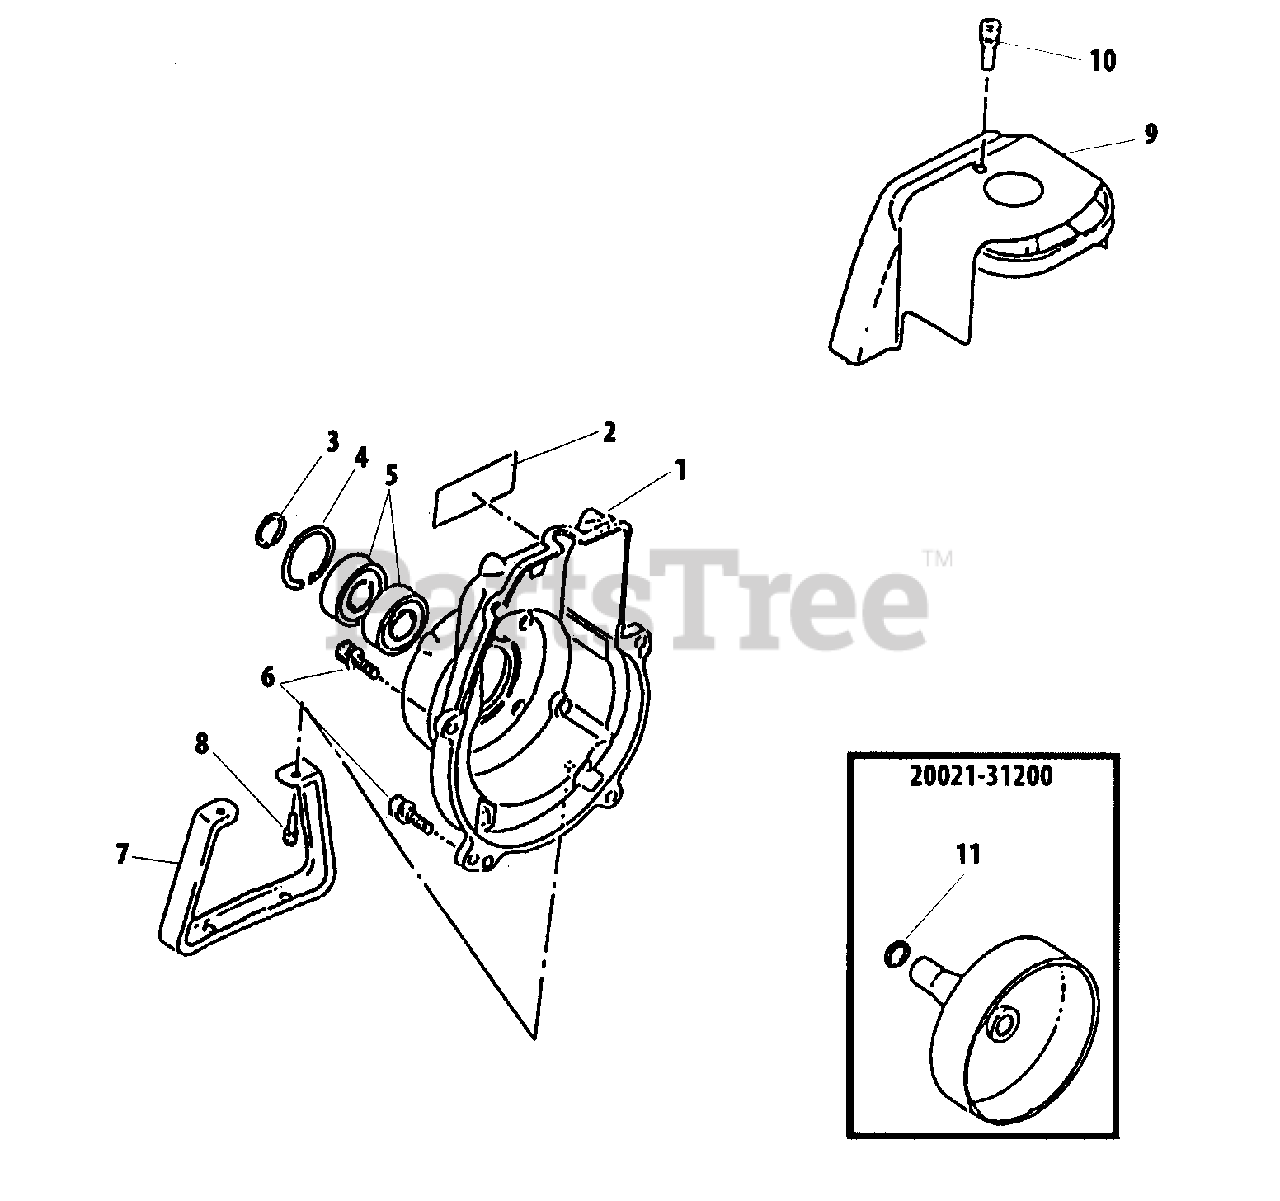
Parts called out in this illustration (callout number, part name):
1	CASE, FAN
2	LABEL - MODEL
3	RING, RETAINING
4	RING, RETAINING - 32
5	BEARING, BALL - 6002
6	SCREW - 5X20
7	STAND
8	SCREW - 5X16
9	COVER, ENGINE
10	SCREW - 5X14
11	RING, RETAINING - 11
20021-31200	CLUTCH DRUM KIT
